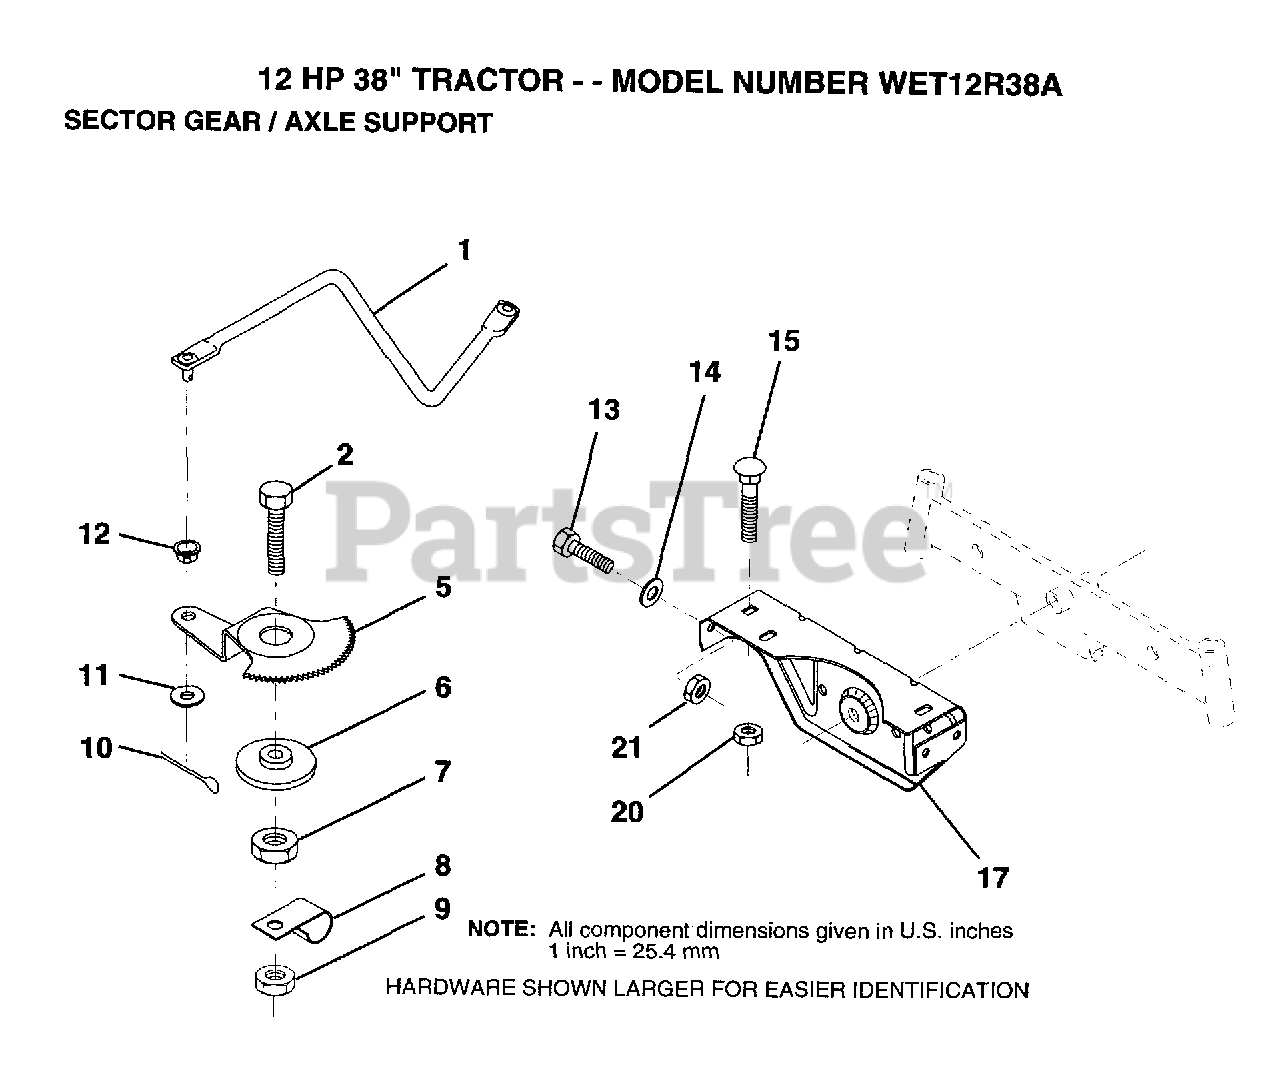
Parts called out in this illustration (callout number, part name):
1	DRAG LINK
2	"BOLT,HEX"
5	GEAR SECTOR
6	BUSHING
7	NUT
8	CLIP INSULATOR
9	NUT LTV
10	COTTER PIN
11	WASHER
12	BUSHING.DRAGLINK
13	BOLT
14	WASHER
15	BOLT
17	SUPT AXLE FRONT
